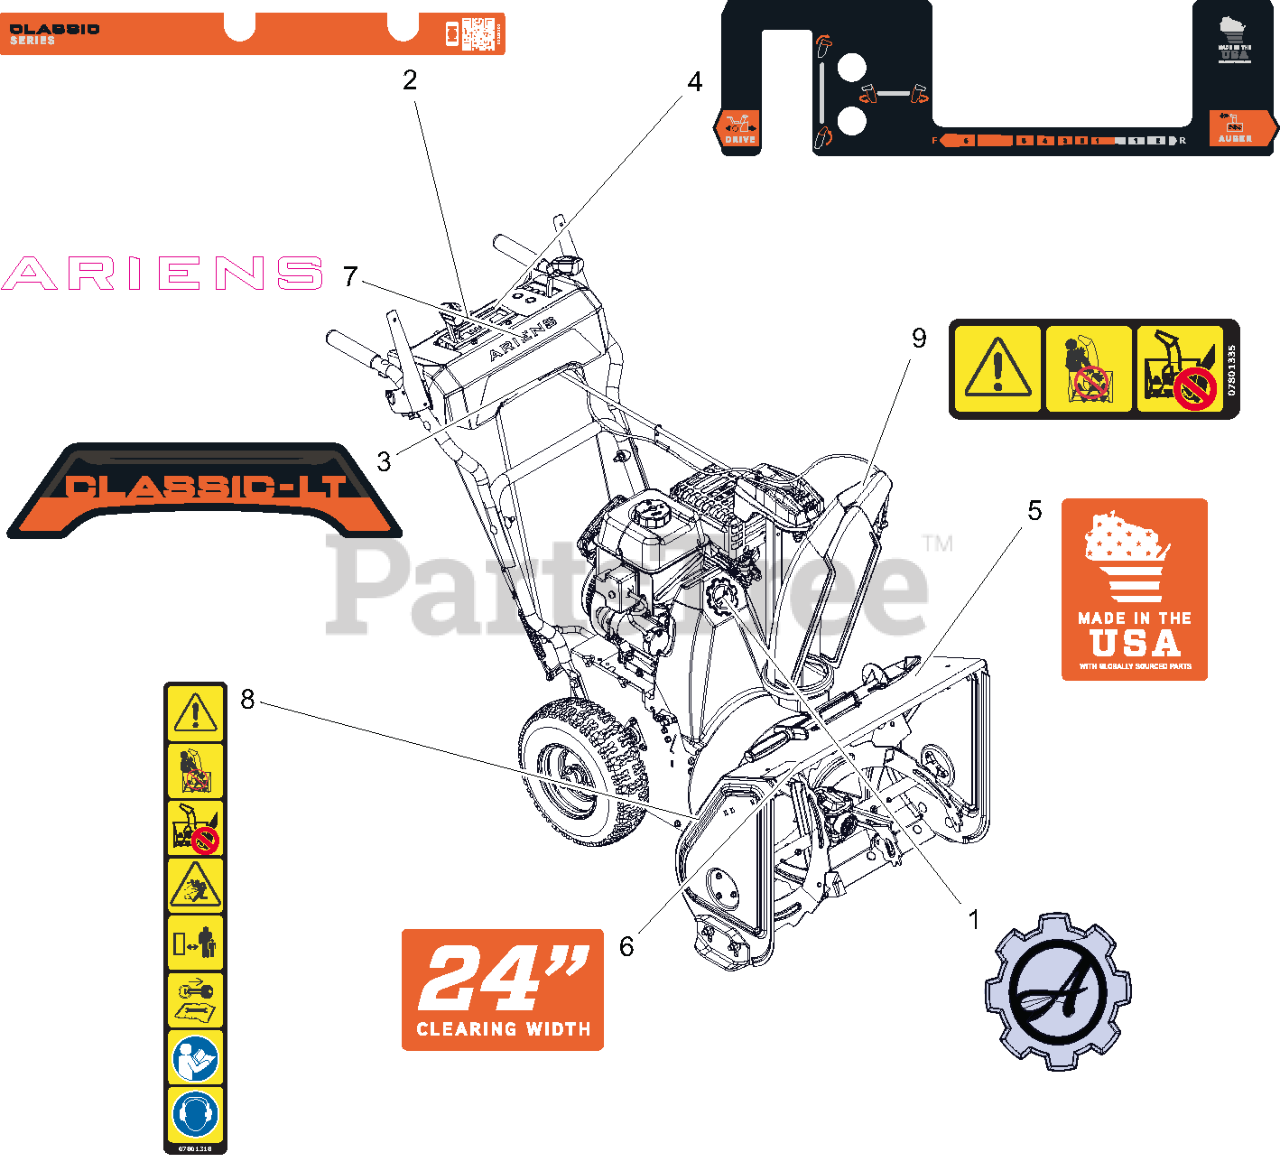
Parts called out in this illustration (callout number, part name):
1	DECAL- ARIENS GEAR BADGE
2	DECAL- DASH - CLASSIC
3	DECAL- BEZEL - CLASSIC LT
4	DASH- CONTROL - SMALL DASH
5	DECAL- MADE IN USA
6	DECAL- CLEARING - 24
7	DECAL- ARIENS - 7.46"
8	DECAL- SAFETY - DANGER
9	DECAL- DANGER
